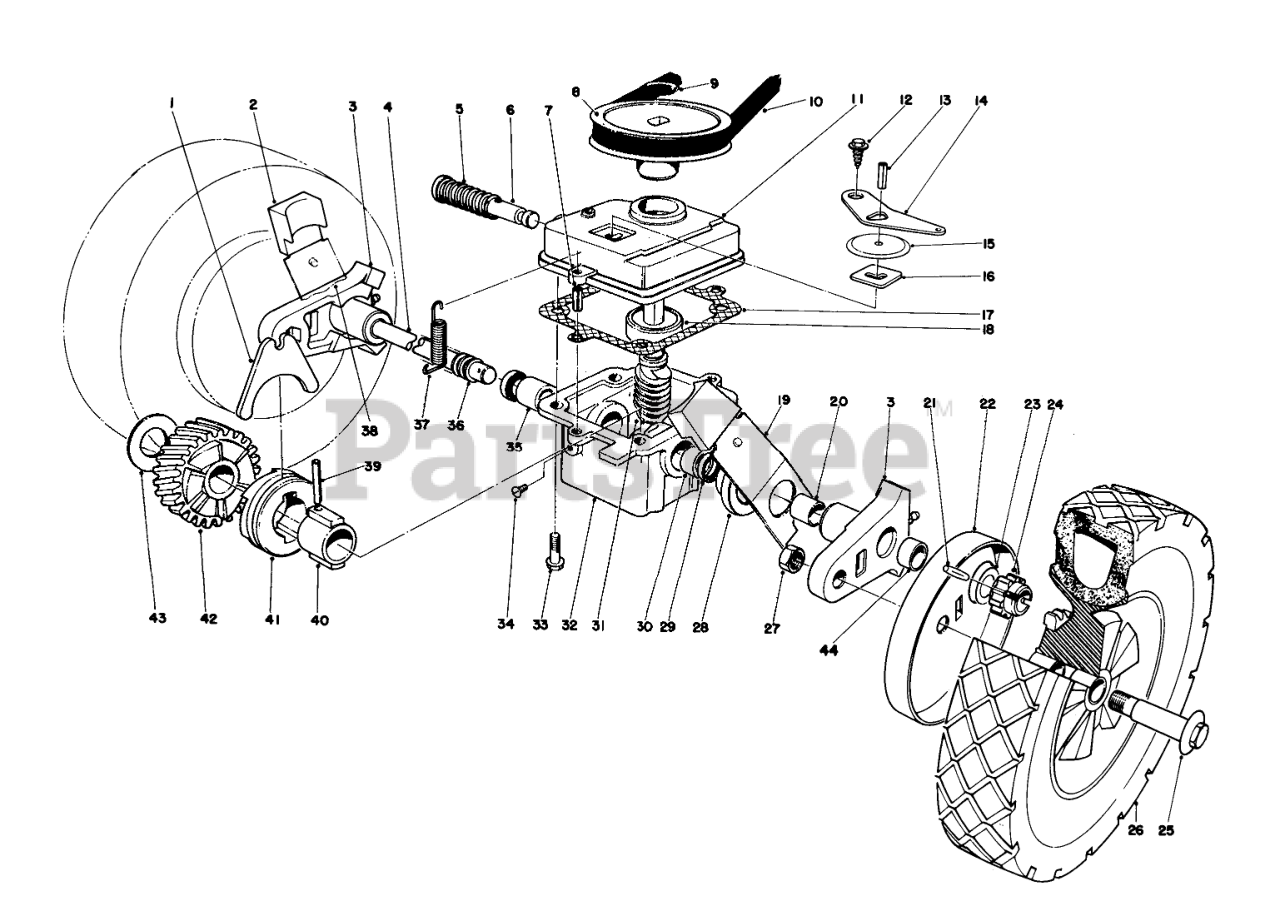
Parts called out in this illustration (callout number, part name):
1	SHIFTER FORK
2	KNOB-ARM
3	Pivot Arm (Incl. Ref. #20 & 40)
4	DRIVE SHAFT (SERVCE)
5	SPRING
6	Shift Rod
7	3/16 X 1/2 ROLL PIN
8	PULLEY
9	Push On Retainer
10	V BELT
11	Cover Gear Case
12	Screw
13	PIN-ROLL, SLOTTED
14	SHIFTER ARM
15	TRANS DUST COVER
16	LATCH PLATE
17	GASKET
18	Bearing
19	SPRING ARM ASM SP LH
20	BUSHING
21	Spiral Pin
22	WHEEL COVER
23	WASHER-THRUST
24	Pinion
25	BOLT-WHEEL
26	Wheel & Tire Assembly
27	Nut
28	End Cap
29	Seal
30	Bushing
31	WORM SHAFT & GEAR
32	Gear Case (Incl. Ref. #29-30 & 35)
33	Screw
34	NYLON SCREW
35	Bushing
36	COVER-SHAFT, DRIVE
37	TENSION SPRING
38	SPRING ARM ASM SP RH
39	Pin
40	SLEEVE
41	CLUTCH JAW
42	Helical Gear
43	THRUST WASHER
44	BUSHING
